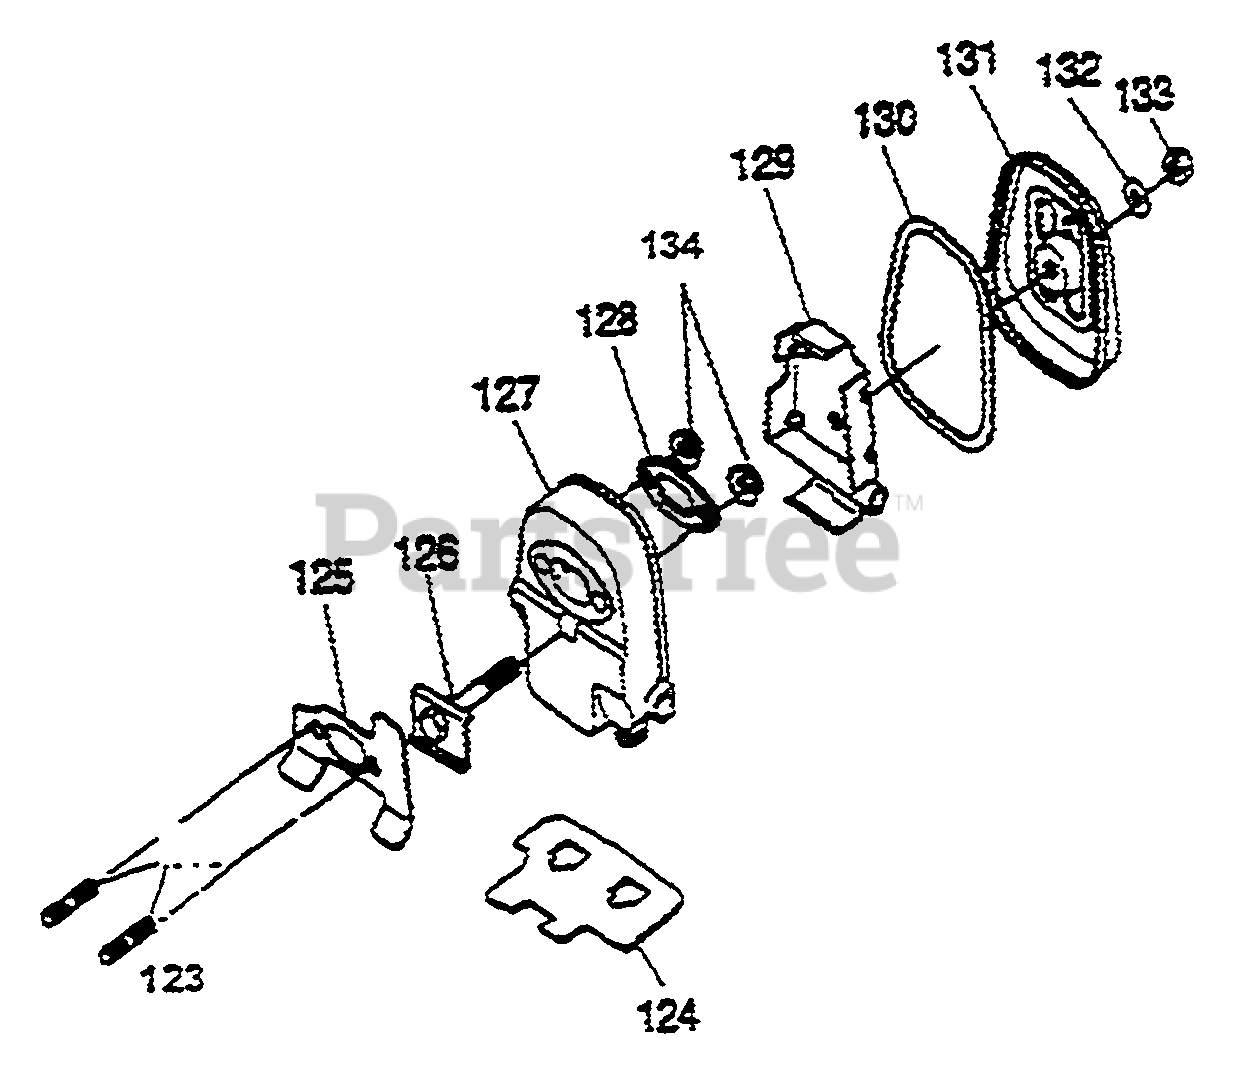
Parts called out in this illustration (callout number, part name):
125	GASKET, MUFFLER
126	BOLT, FLANGE
127	BODY, MUFFLER
130	GASKET MUFFLER SEAL
131	LID, MUFFLER
132	WASHER, SEAL
